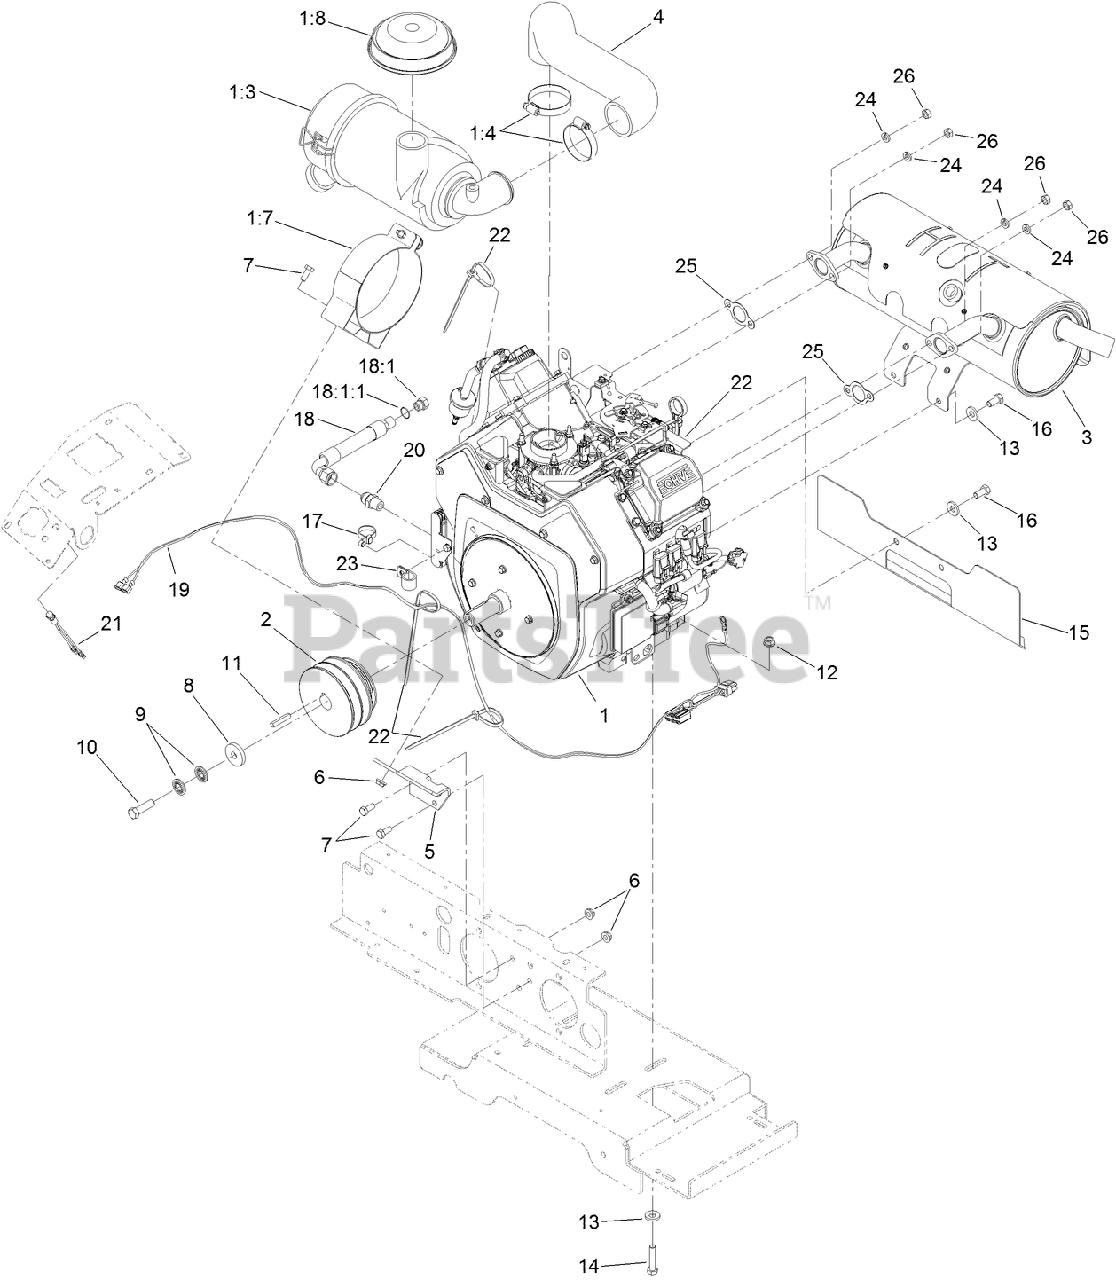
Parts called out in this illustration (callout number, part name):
1:3	AIR CLEANER CANISTER ASM
1:4	CLAMP-HOSE
1:7	BRACKET-FILTER, AIR
1:8	HOOD-CLEANER, 2" AIR INTAKE
2	SHEAVE-ENGINE
3	Muffler
4	Hose-Air Intake
5	BRACKET-FILTER, AIR
6	NUT-HF
7	SCREW-HH
8	WASHER-CLUTCH
9	WASHER-SPRING
10	SCREW-HH
11	KEY-SQUARE
12	NUT-HHF, WHIZ
13	WASHER-BELLEVILLE
14	SCREW-HH
15	SHIELD-EXHAUST
16	SCREW-HH
17	TIE-CABLE
18	OIL DRAIN HOSE ASM
18:1	PLUG-HH
18:1:1	O-RING
19	HARNESS-LIGHT INDICATOR (EFI)
20	FITTING-STRAIGHT
21	INDICATOR-LED, RED
22	TIE-PLASTIC
23	CLIP-LOOM
24	WASHER-LOCK
25	GASKET-EXHAUST
26	NUT-HEX
